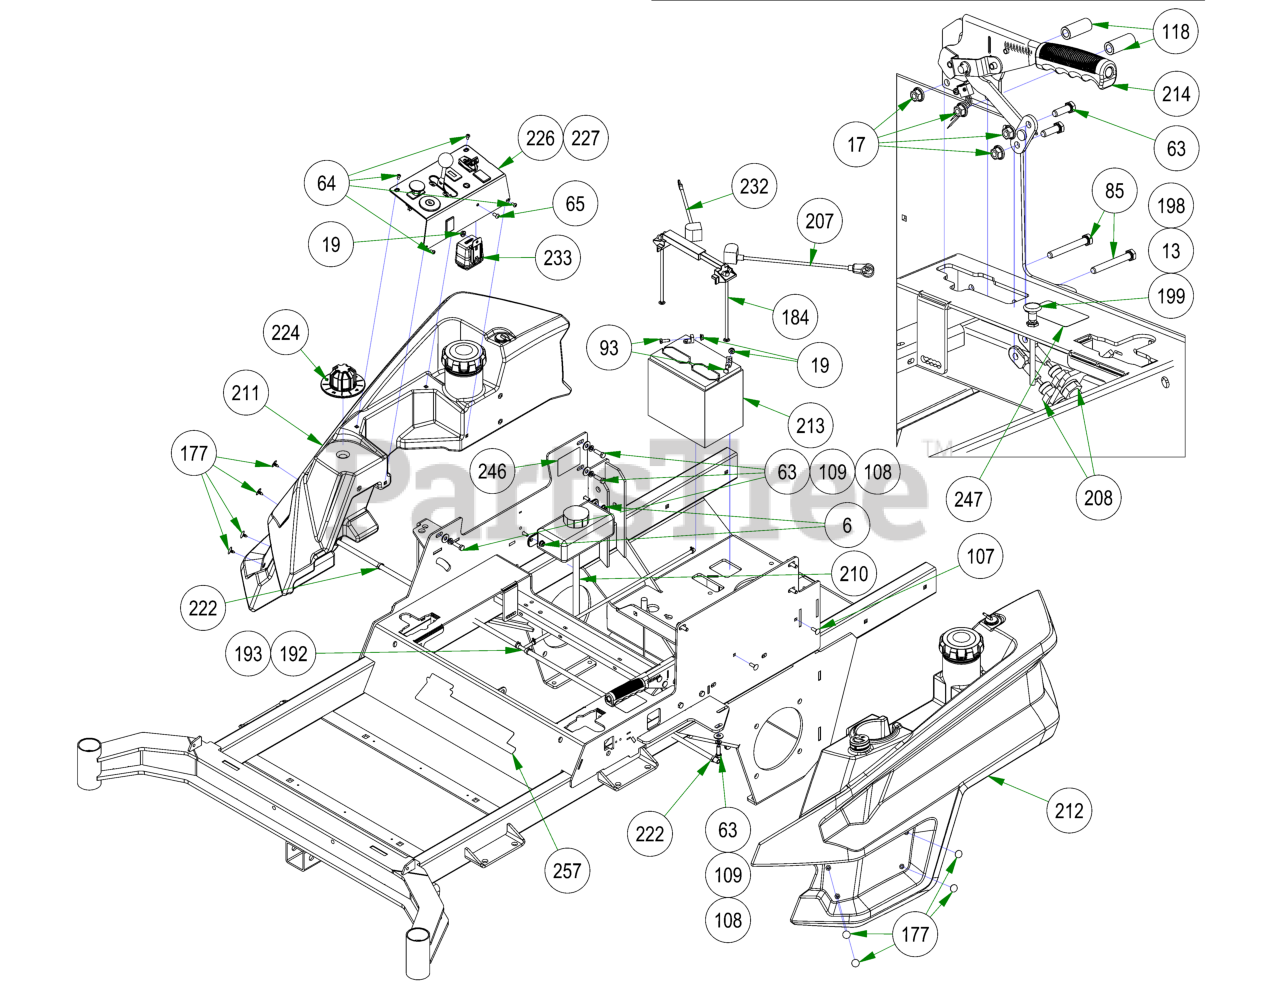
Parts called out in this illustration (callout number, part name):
6	1/4-20 NYL INSERT FLANGE LOCKNUT ZINC
13	3/8-24 HEX NUT ZINC YELLOW
17	5/16-18 NYLON INSERT FLANGE LOCKNUT ZINC
19	1/4-20 HEX SERRATED FLANGE NUT HARD/ZINC
63	5/16-18 X 1 HEX CAP SCREW (GR.5) ZINC
64	10-32 X 3/8 BUTTON SOCKET CAP SCREW 18-8 STAINLESS STEEL
65	1/4-20 X 1/2 BUTTON SOCKET CAP SCREW 18-8 STAINLESS
85	5/16-18 X 2-1/2 HEX CAP SCREW (GR.5) ZINC
93	1/4-20 X 3/4 HEX CAP SCREW (GR.5) ZINC
107	1/4-20 X 3/4 CARRIAGE BOLT (GR.5) ZINC
108	5/16 USS FLAT WASHER (7/8 OD) ZINC
109	5/16 SPLIT LOCKWASHER ZINC
117	MZ Deck Idler Spacer
118	.380 ID X .625 OD X 1.500 LGTH 2019 OUTLAW BRAKE HANDLE
177	3/16 x .48 Christmas Tree Nylon Black
184	Hold Down Assembly
192	2019 Rebel Rogue Renegade Fuel Line for Vanguard & Yamaha
193	2019 Rebel Rogue Renegade Fuel Line for Kawasaki
199	Choke for 36Hp Vanguard & FX1000 Kawasaki
207	14" Red Battery Cable-Base Outlaw
208	Long Brake Cable
210	2019 Rebel Hydro Tank Assembly
211	2019 Right Rebel, Rogue, Renagade Fuel Tank (GAS)
212	2019 Left Rebel, Rogue, Renegade Fuel Tank (GAS)
213	SP-35 Battery
214	2019 Brake Handle Assembly
218	2022 Rebel Frame
222	2 EAR CLAMP 12.5mm-15mm
224	2019 Rigid Deck Dial 1.5 to 5.5
226	Rebel/Rogue Control Panel Assy
226.9	2022 Rebel Control Panel
227	Rebel/Rogue Control Panel Assy-Drive by Wire
227.1	2022 Rebel Control Panel
232	Starter Cable
233	2019 Wiring Harness-Rebel/Rogue
246	Hydraulic Decal
247	2018 Out/XP/Diesel Brake Decal
257	2019 Rebel Cooler Cover Decal
